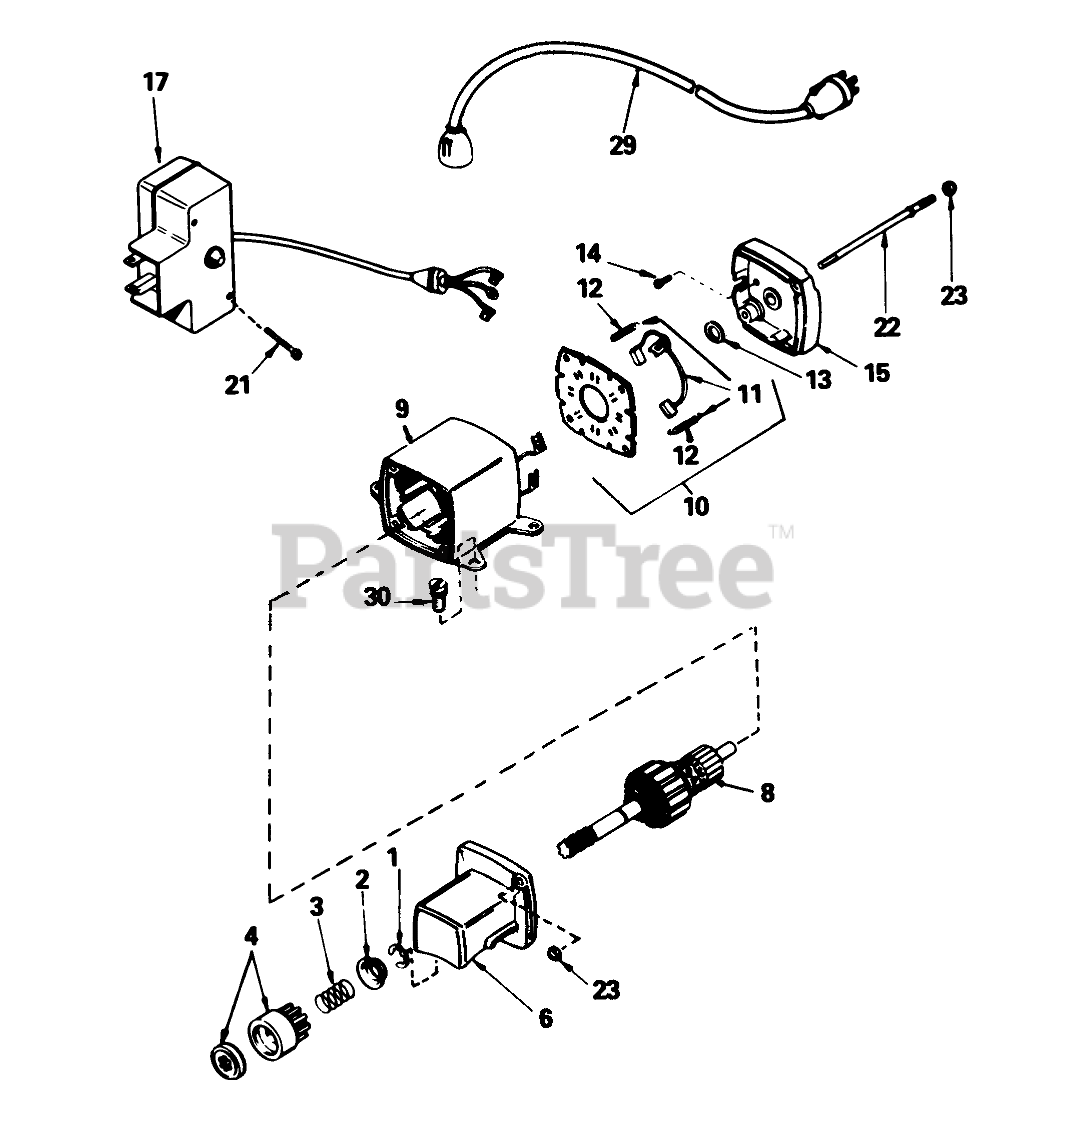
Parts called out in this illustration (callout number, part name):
1	Ring-Retainer
2	Retainer-Spring
3	Spring-Anti Drift
4	Nut & Gear
6	Cap Assy.-Drive End
8	Armature
9	Housing Assy.
10	Card Assy.-Brush (Incl. Ref. #11)
11	Brush & Spring Kit (Incl. Ref. #12)
12	1545D SUP TO W/3256
13	Washer-Thrust
14	Screw-Ground
15	Cap Assy.-Commutator End
17	Box Assy.-Switch
21	Screw
22	Bolt
23	Nut-Lock
29	Cord, Extension (10-)
30	Screw (T-30, 1/4-20 x 23/32)
